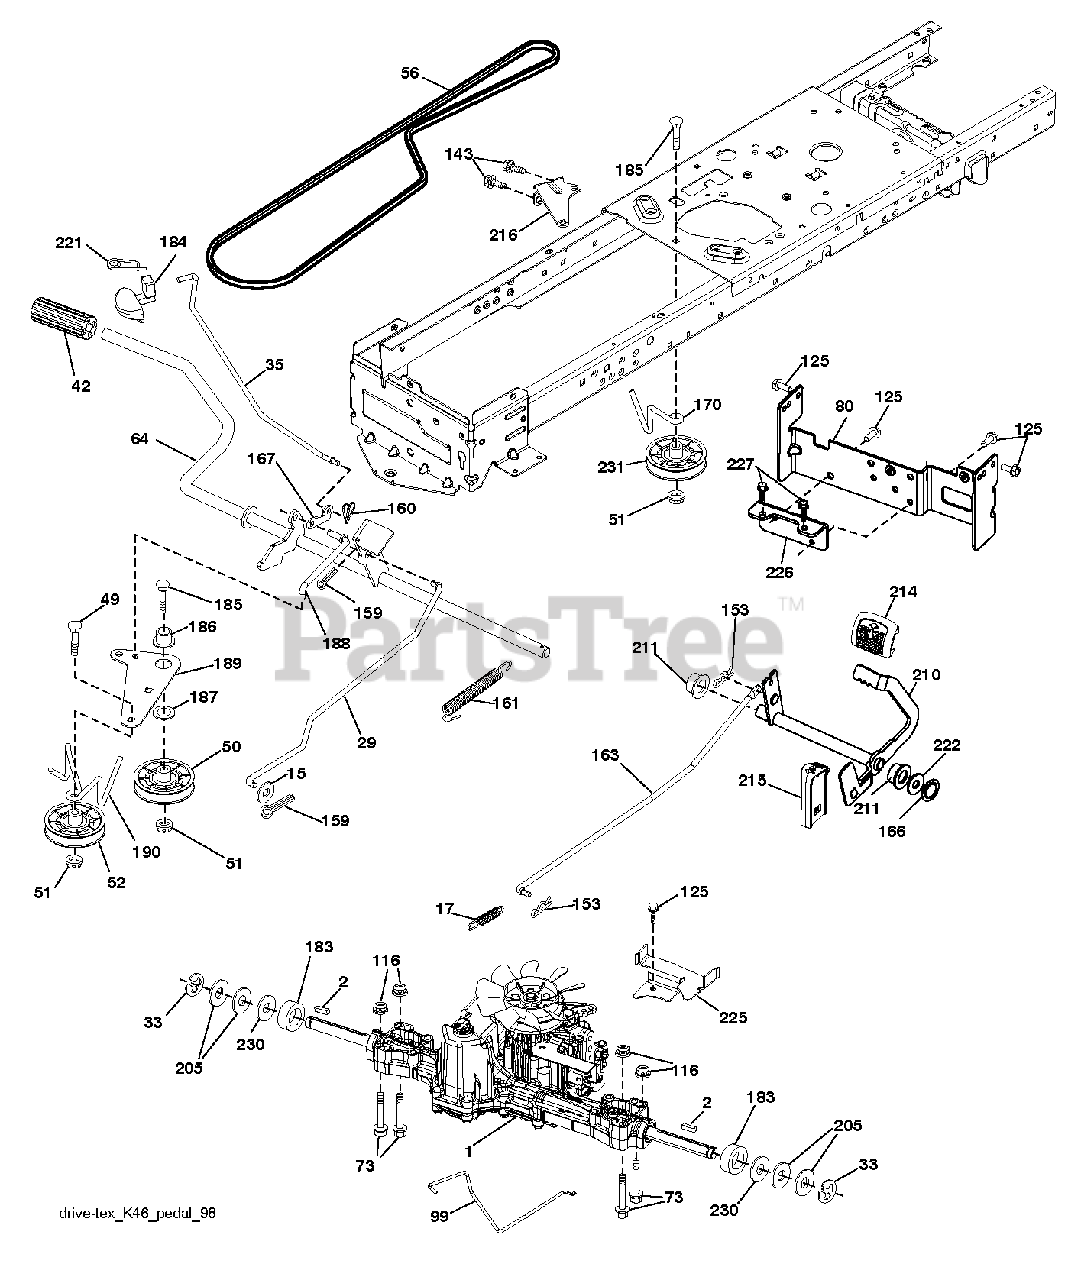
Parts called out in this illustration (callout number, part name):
2	SQUARE KEY
15	WASHER
17	SPRING, BREAK
29	ROD.BRAKE.K46
33	E-RING LT
42	PEDAL COVER T
50	IDLER.FLAT.910.OFFSET
52	IDLER.V-GROOVE.910.OFFSET
64	SHAFT.ASM.PEDAL.BRK.CN
99	ROD.SPRING.BYPASS.K46.LT.Z
116	NUT LOCK HEX FLANGE 5/16-18
125	SCREW
143	SCREW LT
159	COTTER PIN
160	RETAINER CLIP
161	SPRING, RETURN LT
163	ROD.CONTROL.PEDAL.K46
166	NUT.PUSH.625
167	LATCH BRAKE PARKING
170	KEEPER.CENTER SPAN.1.688
183	SPACER AXLE
186	SPACER.RETAINER
188	LINK.CLUTCH.GROUND DRI
189	BELLCRANK.GRDDRIVE.NST
190	KEEPER.BELLCRANK.DRIVE
210	ROCKER.ASM.PEDAL.CONTR
211	BEARING RER
214	PAD PEDAL FORWARD
215	PEDAL.REVERSE.TEX.GT.4
216	BRKT.PULLEY.IDLER.WTEX
221	RETAINER.SPRING.CLIP.H
222	WASHER 21/32 X 1-1/4 X 10 GA.
225	KEEPER.BELT.TRANSAXLE.
226	BRACKET MOUNT TORQUE
231	PULLEY VGROOVE
